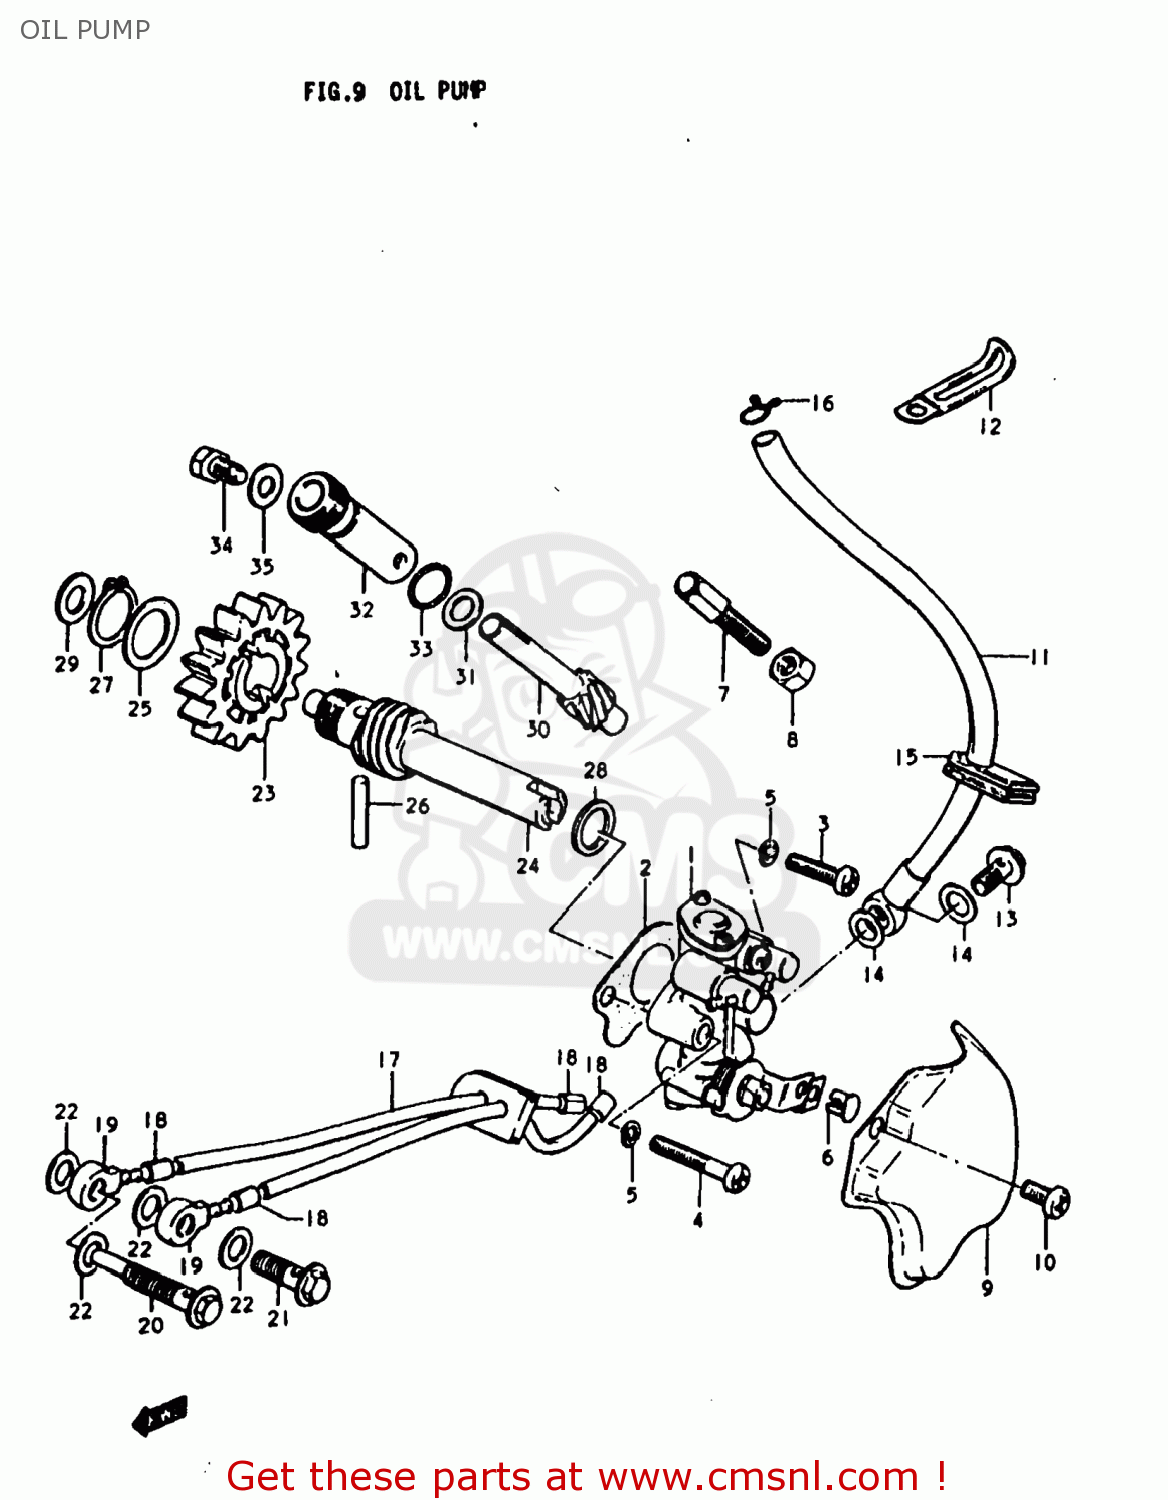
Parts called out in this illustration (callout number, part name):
1	PUMP ASSEMBLY,OIL
2	GASKET,OIL PUMP (MCA)
3	SCREW
4	SCREW
5	LOCK WASHER
6	TERMINAL,CABLE
7	BOLT
8	NUT
9	CAP,OIL PUMP INSPECTION
10	SCREW
11	HOSE,OIL NO.1
12	CLAMP
13	UNION BOLT
14	GASKET(6.2X11X1).2 (NAS)
15	GROMMET
16	CLIP
17	HOSE,OIL NO.2
18	CLIP
19	UNION
20	UNION
21	UNION BOLT
22	GASKET(6.2X11X1).2 (NAS)
23	GEAR,OIL PUMP DRIVE
24	SHAFT,OIL PUMP IDLE GEAR
25	WASHER, INNER
26	ROLLER(4X23.8)
27	CIRCLIP
28	WASHER
29	THRUST WASHER
30	GEAR,TACHOMETER DRIVEN
31	WASHER(8X13.7X1)
32	SLEEVE,TACHOMETER DRIVE
33	O RING(D:1.3,ID:9.6)
34	BOLT
35	WASHER
